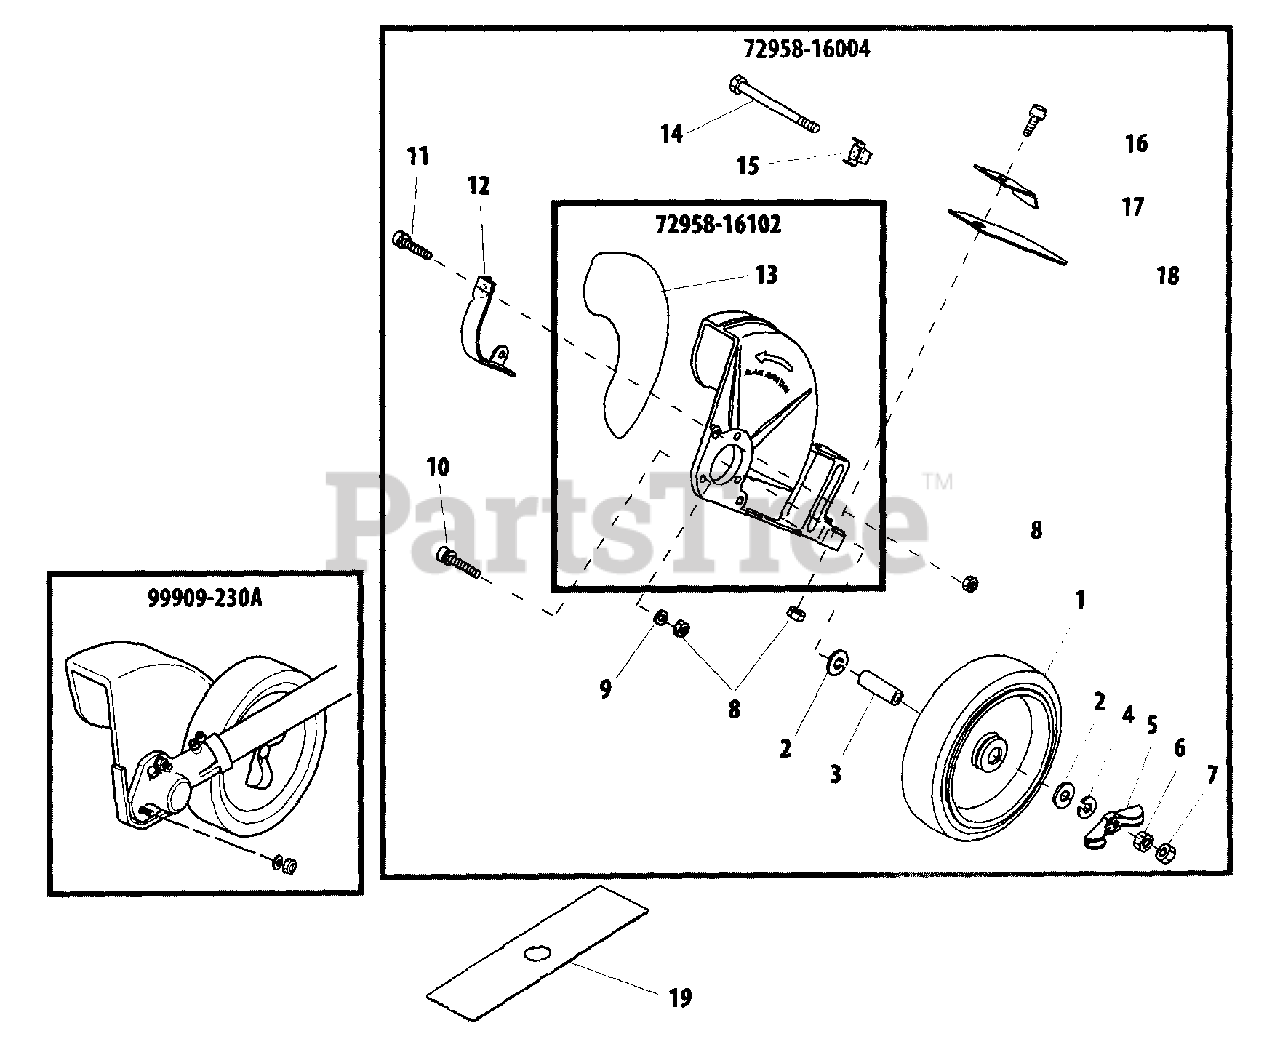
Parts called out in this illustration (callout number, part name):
1	WHEEL
2	WASHER
3	COLLAR
4	LOCKWASHER - 8
5	WINGNUT
6	NUT - 8
7	LOCKNUT
9	LOCKWASHER - 5
10	SCREW - 5X25
11	SCREW - 5X12
12	PROTECTOR
13	LABEL - TRADE
14	BOLT - 8X90
15	BRACKET
16	SCREW - 5X16
17	PLATE
18	DEFLECTOR
19	BLADE, EDGER
72958-16004	GUARD ASSY
72958-16102	GUARD
99909-230A	GEAR CASE KIT
